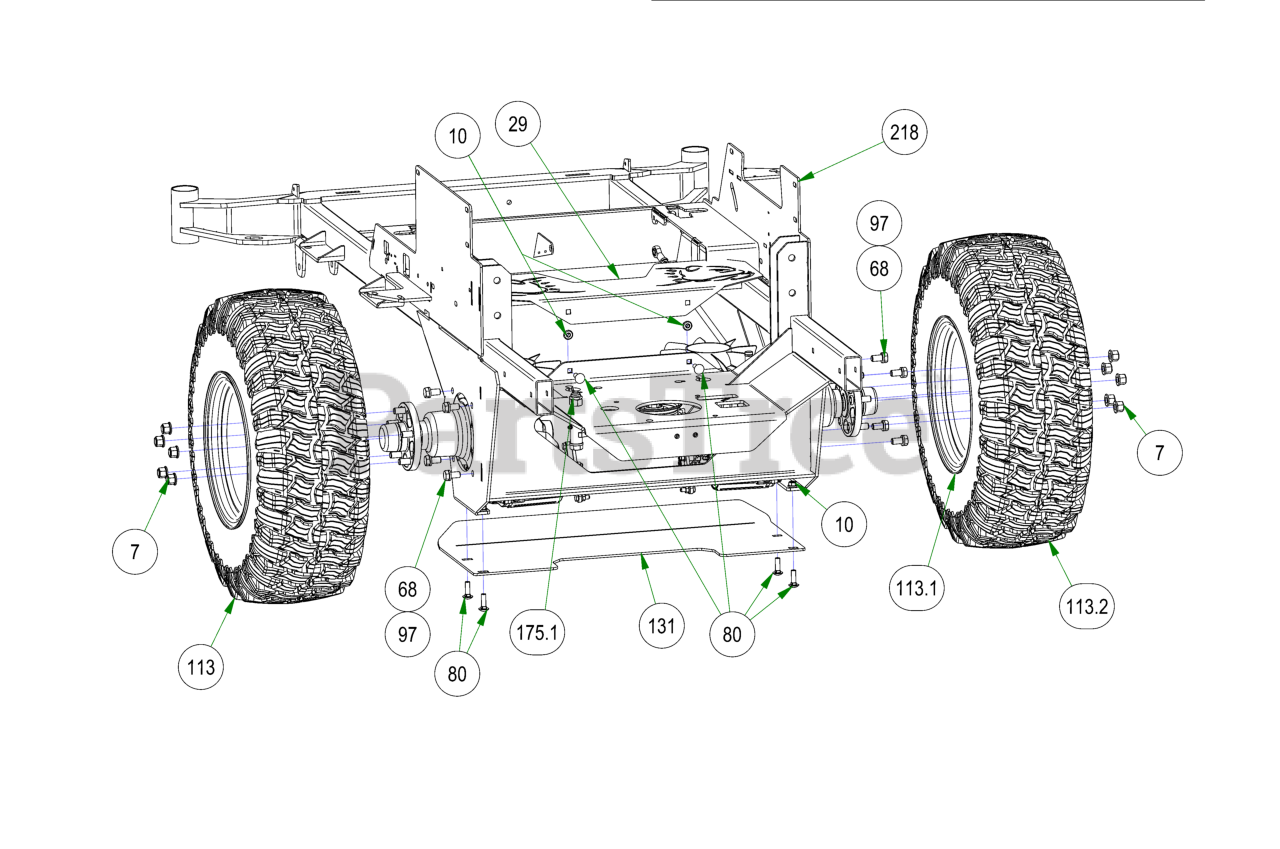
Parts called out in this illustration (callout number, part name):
7	Acorn Lug Nut
8	3/8-16 NYLON INSERT LOCKNUT ZINC
10	3/8-16 NYLON INSERT FLANGE LOCKNUT (GR.F) ZINC
14	1/2-13 HEX NUT ZINC
17	5/16-18 NYLON INSERT FLANGE LOCKNUT ZINC
29	2019 Rigid Fan Guard
61	All Thread
62	5/16-18 X 1-1/4 HEX C/S (GR.5) ZC
63	5/16-18 X 1 HEX CAP SCREW (GR.5) ZINC
68	1/2-13 X 1 HEX CAP SCREW (GR.5) ZINC
73	1/2-13 NYLON INSERT JAM LOCKNUT ZINC
79	3/8-16 X 1-1/4 HEX CAP SCREW (GR.5) ZINC
80	3/8-16 X 1-1/4 CARRIAGE BOLT ZINC
97	1/2 SPLIT LOCKWASHER (GR.8) ZINC/YELLOW
113	24x12-12 Reaper Turf Tire & Wheel Assembly
113.1	12x12" Black Wheel For 2015 Outlaw
113.2	24x12-12 Reaper Turf Tire
120	Drive Arm Transaxle Spacer
131	2019 Outlaw Rigid Skid Plate
163	Deck spring big diameter
164	2019 Rebel Push Rod Assembly
164.1	5/16 LH Nut
164.2	3/8-24 HEX NUT ZINC YELLOW
164.3	2019 Rebel Push Rod
164.4	Spherical Rod End - Outlaw
164.5	Spherical Rod End - Outlaw
172	2015 Outlaw Brake Adapter (4400 Transaxles Only)
175	2019 Rebel Pump Idler
175.1	5/8-11 NYLON INSERT JAM LOCKNUT ZINC
175.2	1/2-13 NYLON INSERT FLANGE LOCKNUT ZINC
175.3	5/8-11 X 4-1/2 HEX CAP SCREW (GR.5) ZINC
175.4	1/2-13 X 2-3/4 HEX CAP SCREW (GR.5) ZINC
175.5	.635 ID X 1.120 OD X .140 THICK FLAT WASHER NYLON
175.6	5/8 SOLID SHAFT COLLAR (W/1 SET SCREW) ZINC
175.7	1/2 SOLID SHAFT COLLAR (W/1 SET SCREW) ZINC
175.8	4 3/4" Idler Pulley
175.9	Deck Idler
181	2019 Rebel Pump Belt
190	4400 Transaxle-Left-Base Outlaw/2019 Rebel
190.1	Gold Transaxle Spring
190.2	Fan/Pulley Kit for 4400 Outlaw
190.3	Hub for 4400 Transaxle
190.4	Seal Kit for 4400 Series Outlaw Transaxle
190.5	Hydro Filter for 4400 Transaxle
191	4400 Transaxle-Right-Base Outlaw/2019 Rebel
191.1	Gold Transaxle Spring
191.2	Fan/Pulley Kit for 4400 Outlaw
191.3	Hub for 4400 Transaxle
191.4	Seal Kit for 4400 Series Outlaw Transaxle
191.5	Hydro Filter for 4400 Transaxle
218	2022 Rebel Frame
